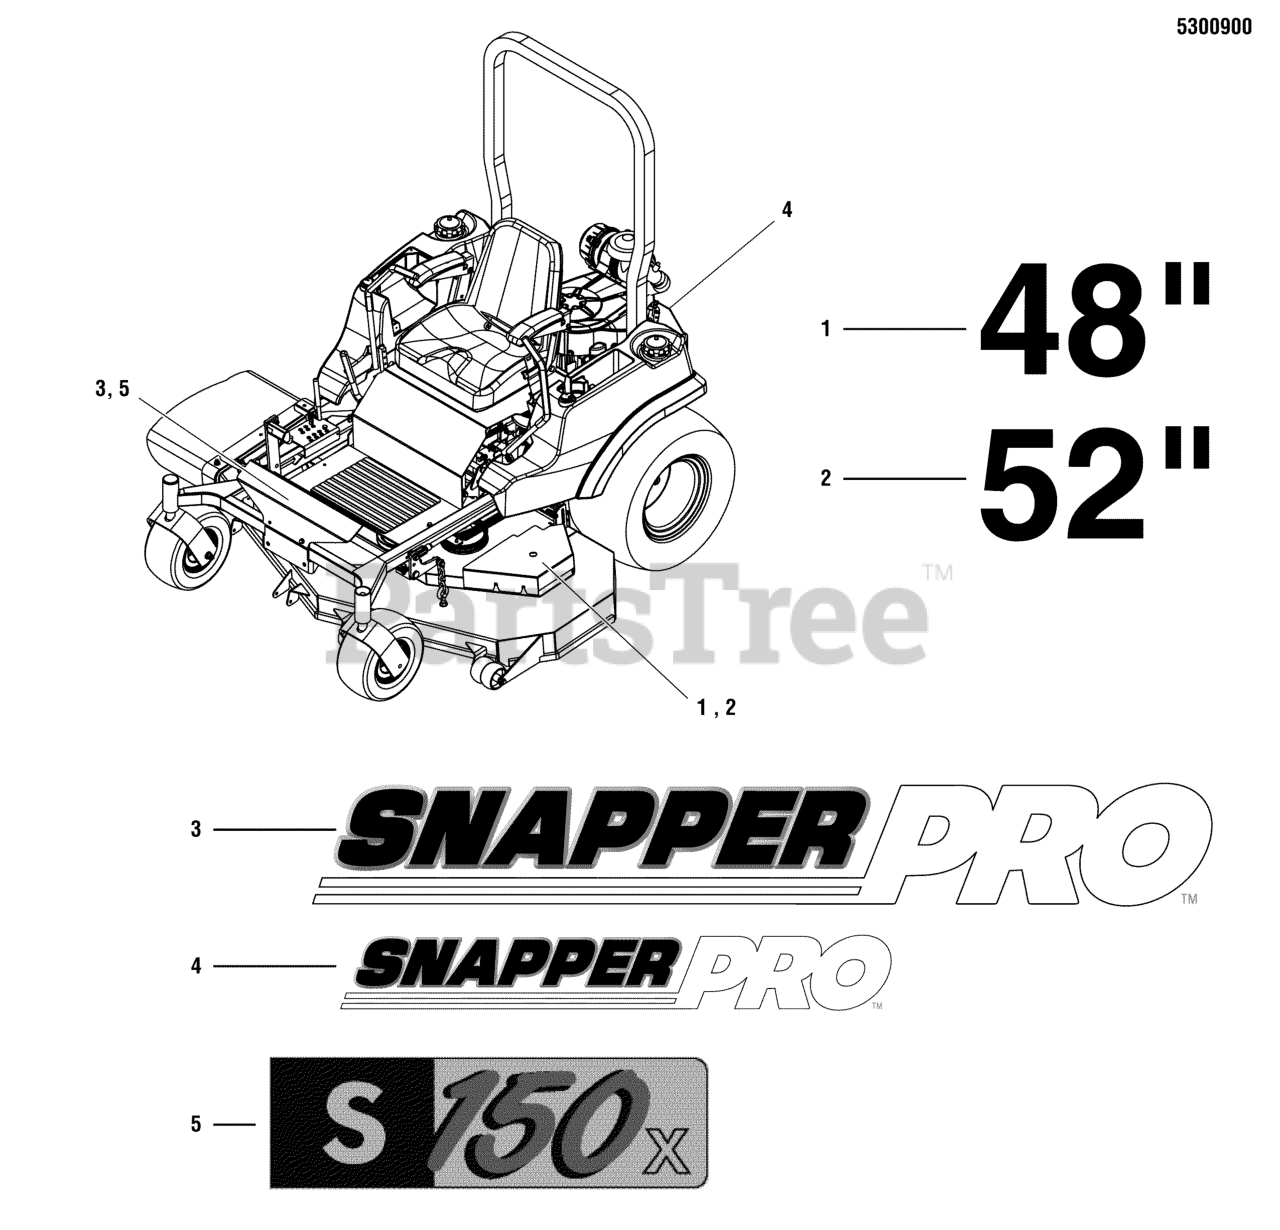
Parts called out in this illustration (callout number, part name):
1	DECAL, 48
2	DECAL, 52
3	DECAL, S150X, FRONT
4	DECAL, SNAPPER PRO, HEAT
5	DECAL, S150X
